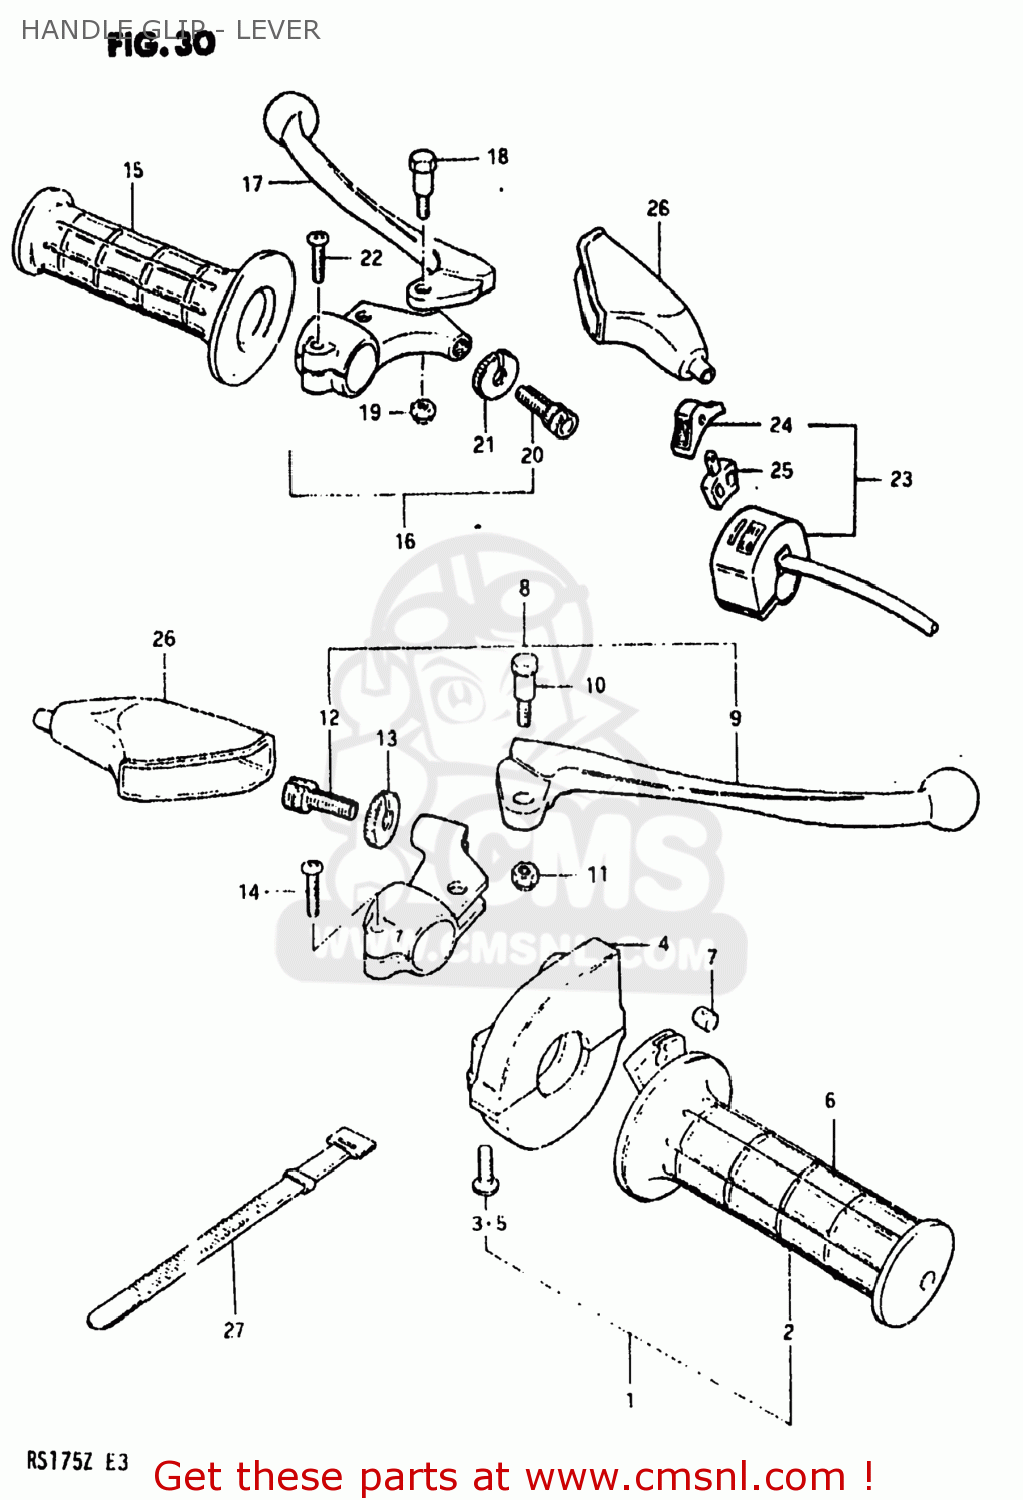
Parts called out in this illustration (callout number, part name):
1	CASE ASSEMBLY,THROTTLE
2	GRIP,THROTTLE
3	SCREW
4	CASE,THROTTLE
5	SCREW
6	CASE ASSEMBLY,THROTTLE
7	PIECE,THROTTLE END
8	LEVER ASSY,BRAKE
9	LEVER,BRAKE
10	BOLT,LEVER
11	NUT 6MM
12	ADJUSTER,CABLE
13	NUT,CABLE ADJUSTER
14	SCREW
15	GRIP,LEFT
16	LEVER ASSY,CLUTCH
17	LEVER,CLUTCH
18	BOLT,LEVER
19	NUT 6MM
20	ADJUSTER,CABLE
21	NUT,CABLE ADJUSTER
22	SCREW
23	SWITCH,DIMMER
24	KNOB,LIGHTING & DIMMER
25	BLOCK,LIGHTING/DIMMER
26	COVER,CLUTCH LEVER
27	CLAMP(L:120)
